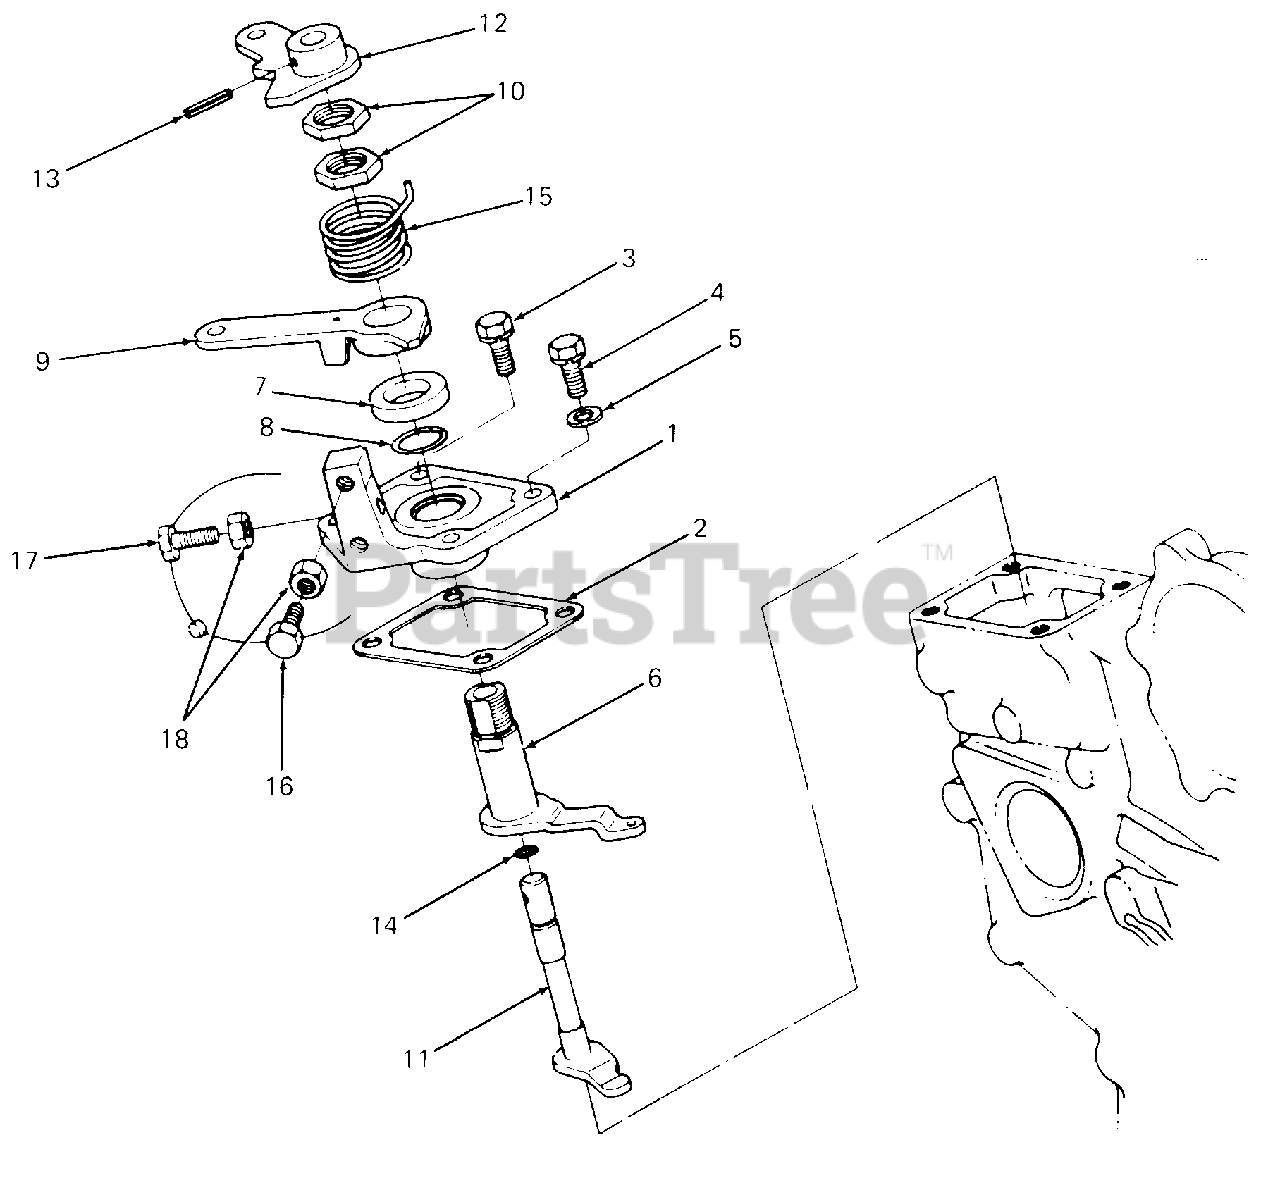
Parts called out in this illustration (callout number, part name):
1	Plate, Speed Control
2	Gasket
3	Screw Hex Cap w/Washer
4	Screw Hex Cap w/Washer
6	Lever, Governor
8	O-Ring, 5/8 X 3/4
9	Lever, Speed Control
12	Lever, Engine Stop
13	Pin, Slotted Spring
14	O-Ring, 5/32 X 9/32
15	Spring, Return
17	Screw, Hex Cap
